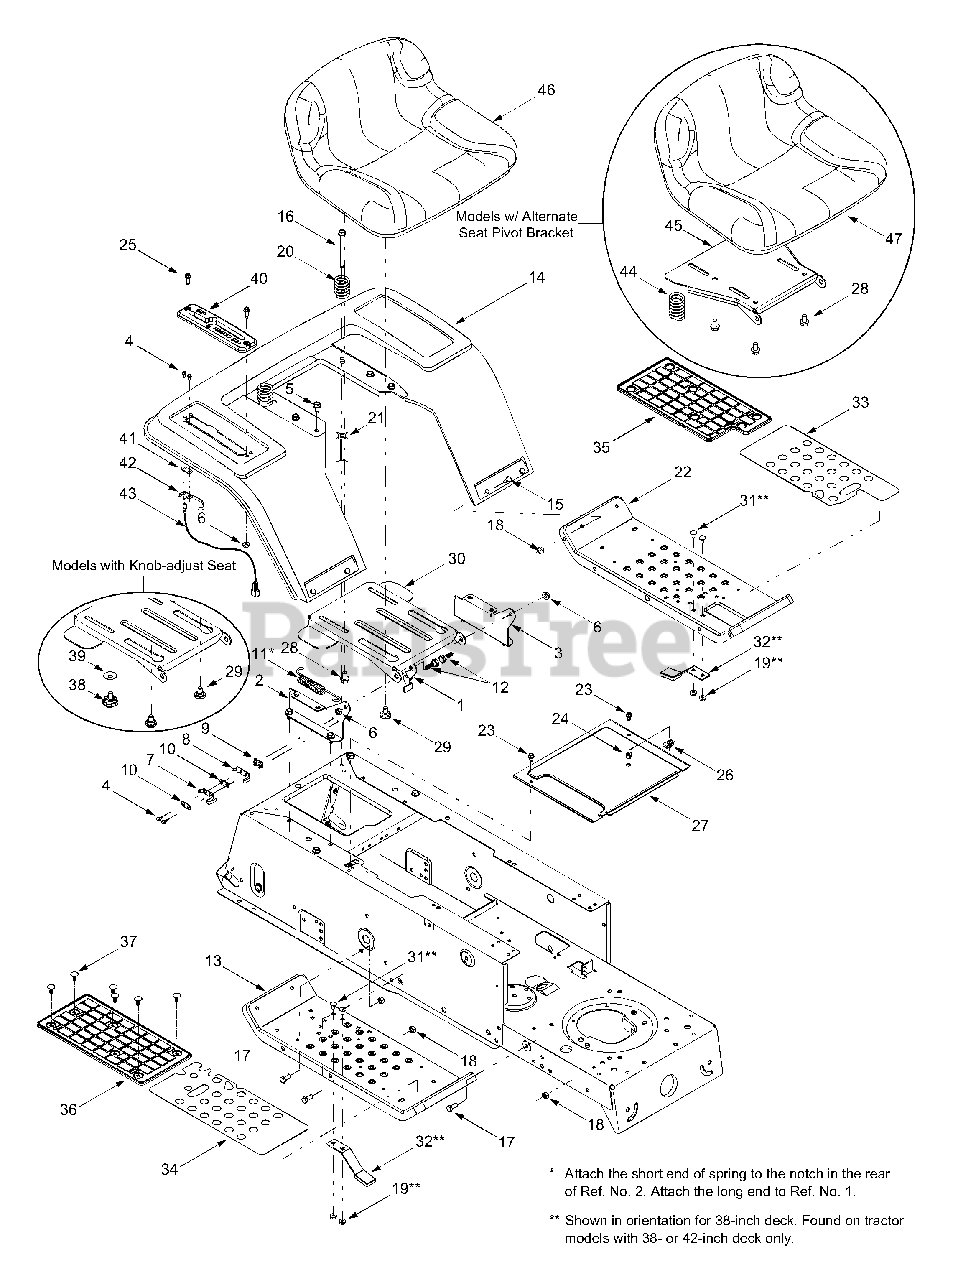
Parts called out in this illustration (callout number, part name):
1	Seat Lift Bracket
4	Self-tapping Screw, #8-18 x .50
5	Self-tapping Screw, 5/16-12 x .75
6	Flange Lock Nut, 5/16-18
7	Outer Seat Spring Switch
8	Inner Seat Spring Switch
9	Insulator Plate Boss
10	Insulator Plate
11	Extension Spring, .75 x 5.31
12	Shoulder Screw, .437 x .286
16	Self-tapping Screw, 5/16-18 x 3.5
17	Hex Screw, 5/16-18 x .75
18	Nylon Lock Nut, 5/16-18
19	Flange Lock Nut, 1/4-20
20	Compression Spring, 1.314 x 1.8
21	Spacer
24	Snap Bushing, 1/4
25	Self-tapping Screw, 1/4-20 x .75
26	U-Clip Nut, 1/4-20
29	Shoulder Screw, .625 x .175, 3/8-16
31	Carriage Screw, 1/4-20 x .50
32	Blade Spindle Brake Assembly
33	LH Abrasive Foot Pad
34	RH Abrasive Foot Pad
35	LH Rubber Foot Pad
36	RH Rubber Foot Pad
37	Ratchet Clip, .250 Dia
38	Knob, 3/8-16 X .625
39	Bell Washer, .389 x 1.120 x .030
40	Speed Index Bracket
41	Insulator Nut Plate
42	Spring Switch
43	Wire Extension, Reverse
44	Compression Spring, 1.314 x 2.55
46	Low Back Seat, Black
47	Low Back Seat, Black
